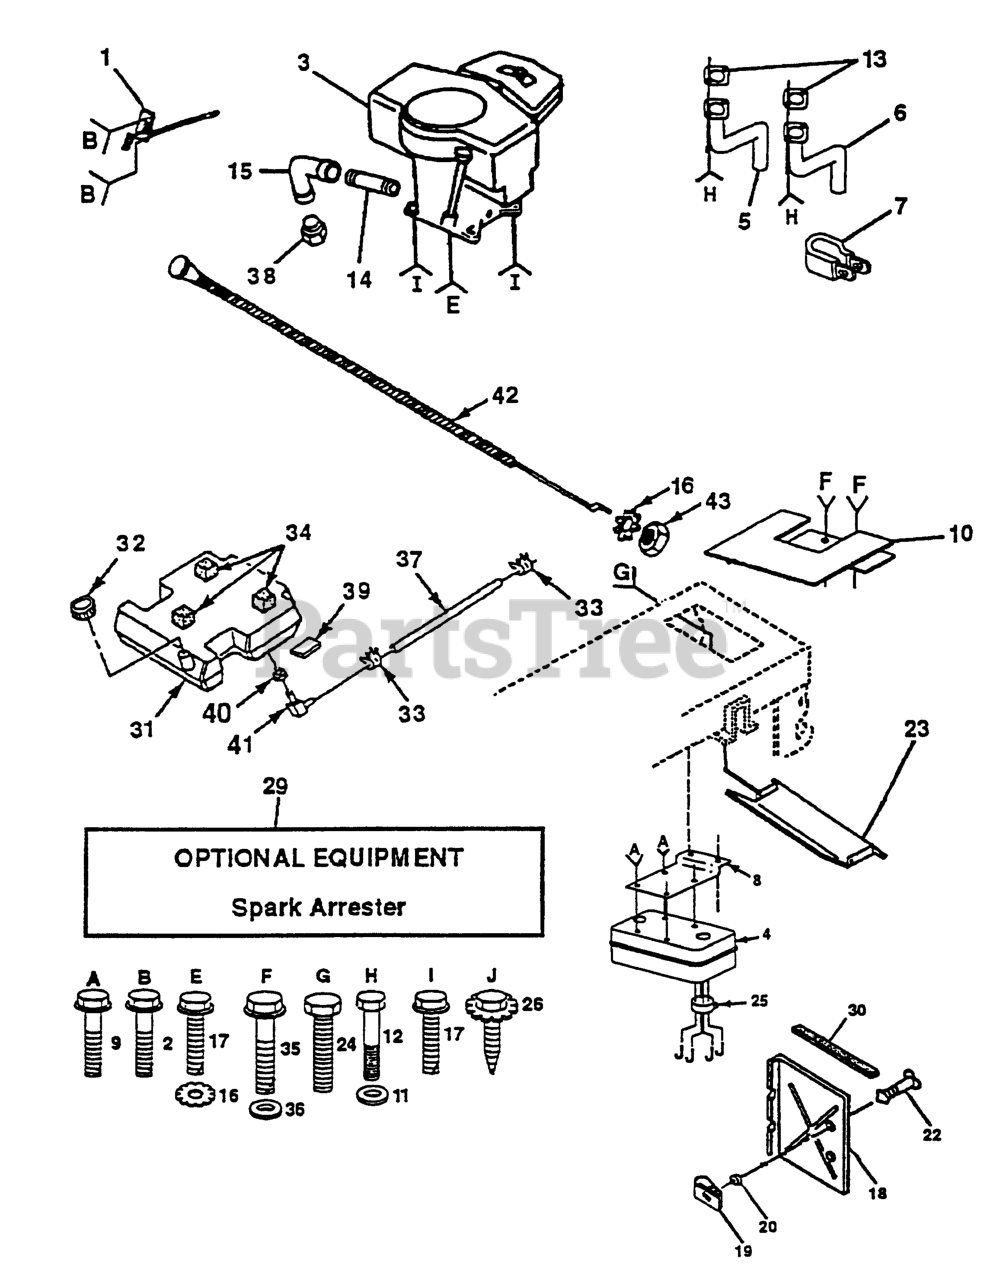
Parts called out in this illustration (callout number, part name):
1	CONTROL.THROT.RH.BLK.FLG.44.75
2	SCREW LT
5	TUBE ASSY EXH LH
6	TUBE ASSY EXH RH
8	BRACKET MUFFLER
9	SCREW ST
10	HEAT SHIELD
13	Muffler Gasket
14	Nipple Pipe 3/8 Npt X 4-1/2"
15	ELBOW
16	LOCKWASHER
17	SCREW
18	HEAT SHIELD
19	RECEPTACLE LT
20	RETAINER LT
22	STUD 1/4 TURN
23	HEAT SHIELD
25	DEFL MUFFLER LTV
26	SCREW
29	KIT.SPARK ARRESTOR 794945 B&S
30	FOAM-STRIP LT
31	TANK, FUEL/SENSOR
32	GAS CAP
33	HOSE CLAMP
34	PAD-SPACER LT
35	SCREW.THDROL.5/16-18X3/4.TTY
36	WASHER
37	FUEL LINE 54"
38	Plug Oil Drain
39	IDLER PAD
40	BUSHING OUTLET T
41	STEM FUEL TANK
42	CHOKE CONTROL
43	NUT
